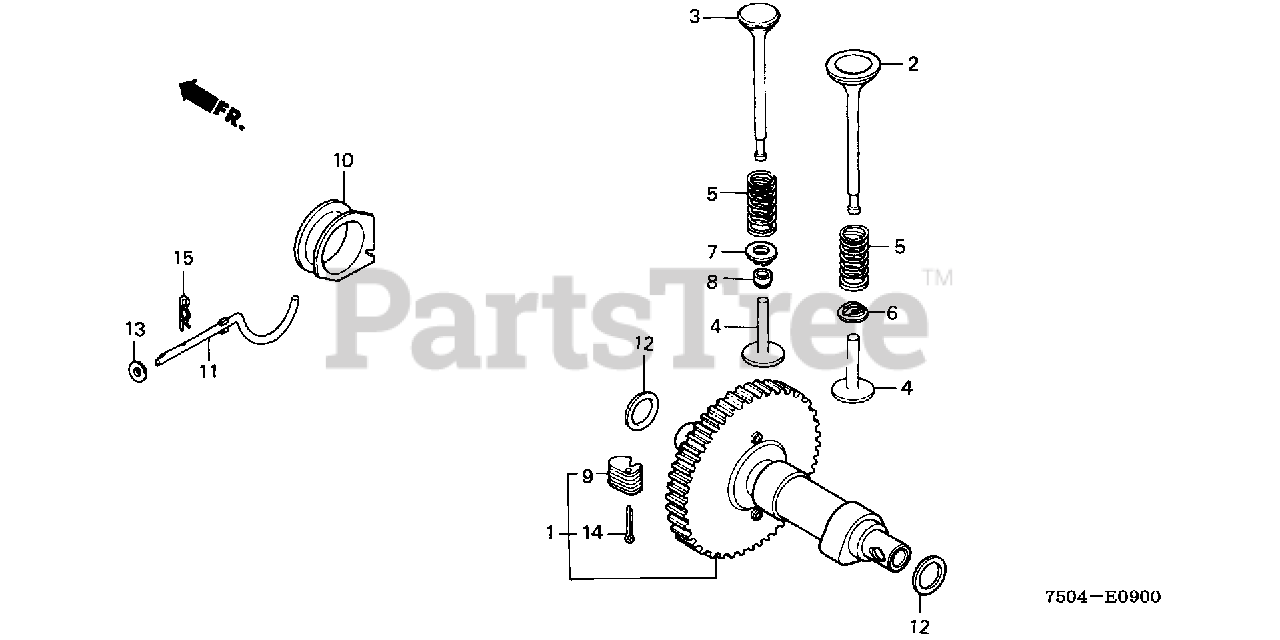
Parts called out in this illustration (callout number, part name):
1	CAMSHAFT ASSY.
2	VALVE, IN.
3	VALVE, EX.
4	LIFTER, VALVE (45.89MM)
4	LIFTER, VALVE (46.04MM)
4	LIFTER, VALVE (46.19MM)
4	LIFTER, VALVE (46.34MM)
5	SPRING, VALVE
6	RETAINER, VALVE SPRING
7	RETAINER, VALVE SPRING
8	ROTATOR, EX. VALVE
9	WEIGHT, GOVERNOR
10	SLIDER, GOVERNOR
11	SHAFT, GOVERNOR
12	WASHER, THRUST (18MM)
13	WASHER, PLAIN (6MM)
14	PIN, COTTER (3.0X45)
15	PIN, LOCK (10MM)
